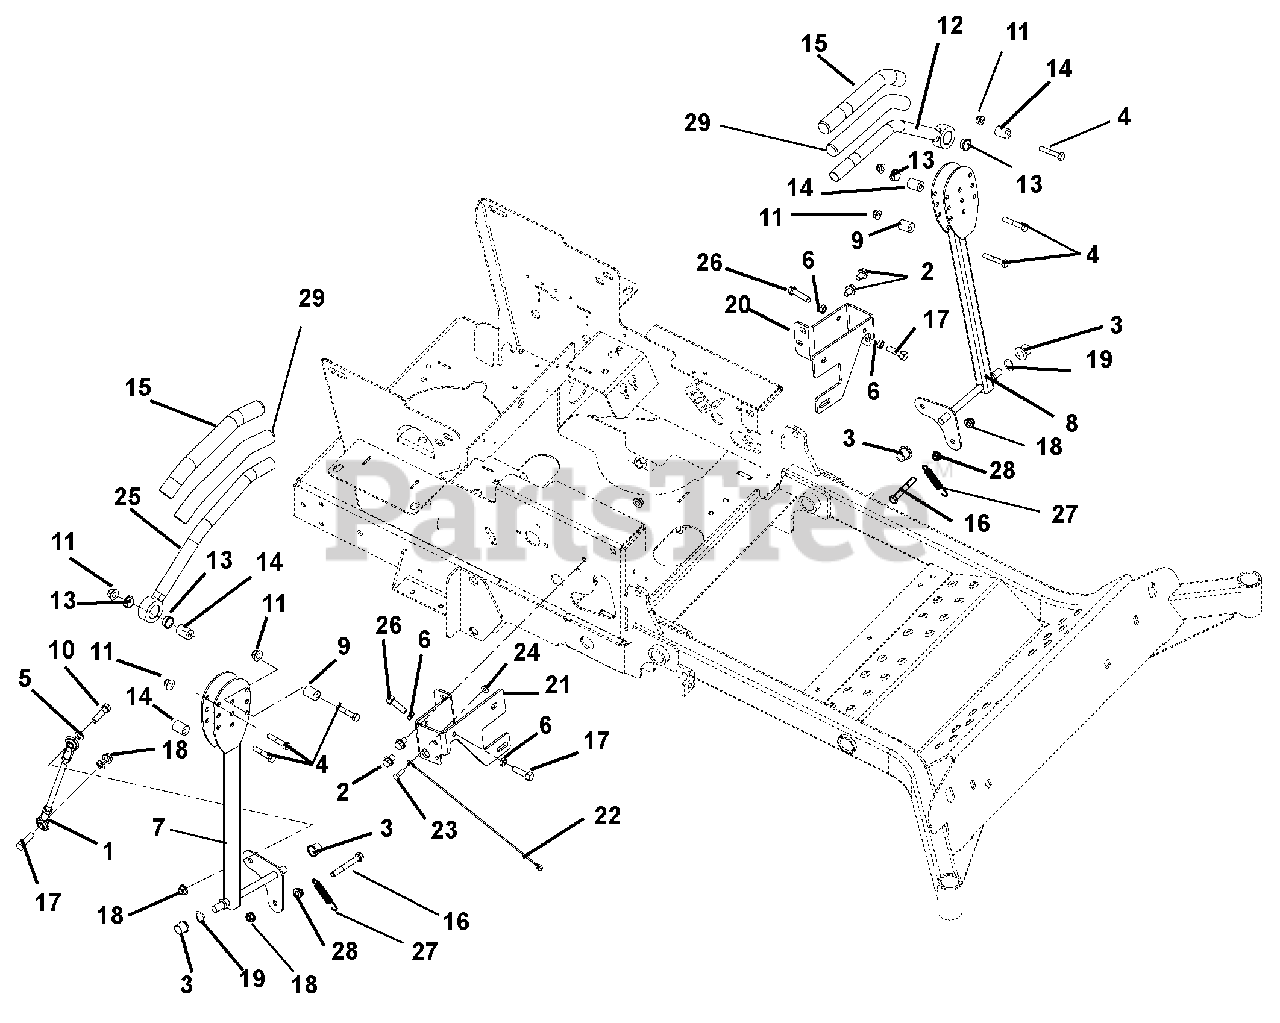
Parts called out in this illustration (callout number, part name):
1	Assembly, Steering Linkage
2	Screw, Tapping .38-16 x .50 Hex Washer Head
3	Bushing Flange .515 x .750 x .745 x 1.00 Nylon
4	Bolt, Hex .31-18 x 1.75 Grade 5
5	Washer, Locking .38 x .094
6	Nut, Hex Jam .375-16
7	Weldment, RH Control Arm
8	Weldment, LH Control Arm
9	Eccentric
10	Bolt, Hex .38-16 x 1.50 Grade 5
11	Nut, Nyloc Flange .375-16
12	Handle Weldment Left-Hand
13	Bushing, Flange Nylon .762 x 1.48 x .44
15	Grip, Handlebar
16	Bolt, Hex .38-16 x 2.75 Grade 5
17	Bolt, Hex .38-16 x 1.25 Grade 5
18	Nut, Nyloc Flange 3/8-16
19	Wave Washer
20	Stop, Steering-Left Hand
21	Stop, Steering-Right Hand
22	Cable, 12.0 LANYARD, Nylon
23	Bolt-Hex .25-20 x .75 Grade 5
24	Nut, Nyloc Flange .25-20
25	Handle Weldment Right-Hand
26	Bolt, Hex .38-16 x .75 Grade 5
27	Spring, External,.061 x .50 x 3.0
28	Nut-Spin Lock-Flange .375-16
